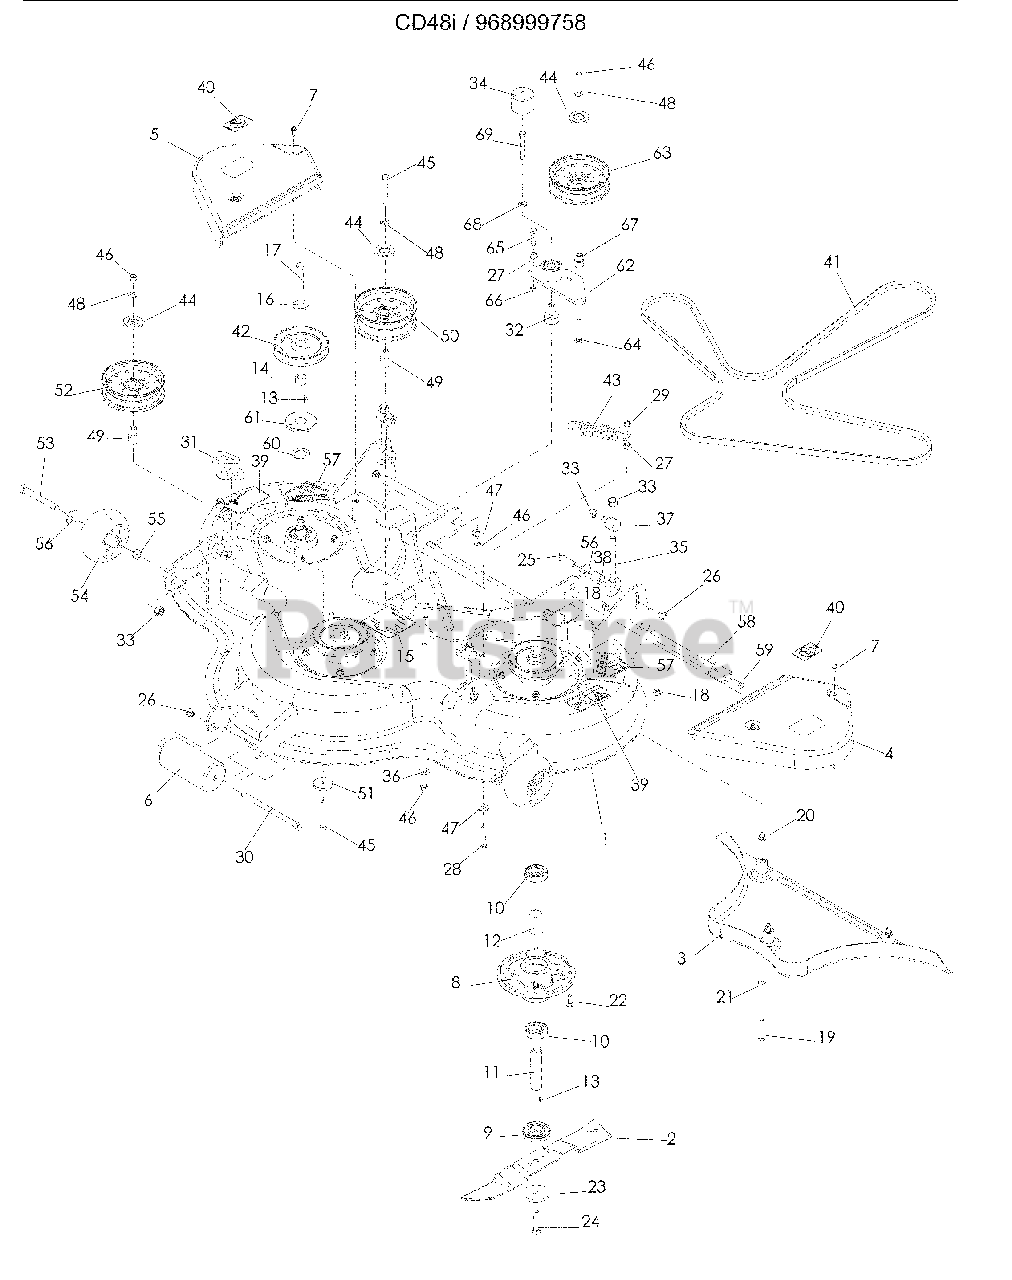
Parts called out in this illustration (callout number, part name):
1	DECK w/ DECALS
2	BLADE
3	PLUG, MULCH
4	BELT SHIELD, LEFT
5	BELT SHIELD, RIGHT
6	ROLLER
7	SCREW ¼-20 x 5/8 SLF TAP
8	BEARING HOUSING
9	BUSHING, BLADE
14	KEY RETAINER
15	DECAL, BELT ROUTING
17	HCS M12 x 1.75 x 60,GR8.8
18	NUT 5/16-18 NYLOC
19	HCS M8 x 1.25 x 50, GR8.8
21	WASHER 5/16 SAE
22	RHSNB 5/16-18 x 1
24	HCS M12 x 1.75 x 50, GR8.8
25	HCS 7/16-14 x 1¾
26	NUT 7/16-14 CTRLK, GR
27	NUT 3/8-16 WHIZLK
28	HCS 3/8-16 x 2
29	NUT 3/8-16 JAM, NYLOC
30	HCS 7/16-14 x 7
32	PIVOT, BEARING
33	NUT ½ NYLOC
34	CAP, VINYL
36	SUPPORT WASHER
39	DECAL, BELT DRIVE
40	DECAL, NO STEP
41	DECK BELT, 52"
42	PULLEY, 48
44	SHIELD, DUST
45	HCS 3/8-16 x 2¾
46	NUT 3/8-16 NYLOC
47	WASHER 3/8
48	WASHER 3/8 THICK
49	IDLER BUSHING
50	IDLER PULLEY
51	HEAVY WASHER
52	IDLER PULLEY
53	HCS ½-13 x 4
54	WHEEL, GAUGE
57	DECAL, CPSC
59	HCS 5/16-18 x 1
61	DUST CAP, BOTTOM
62	ARM w/ BEARINGS, IDLER
63	IDLER PULLEY
64	BOLT 3/8-16 x 2½
65	HCS 3/8-16 x 1½ GR8
66	NUT 3/8-16 JAM
67	BUSHING, IDLER
68	WASHER ½ BELLEVILLE
69	HCS ½-13 x 3
